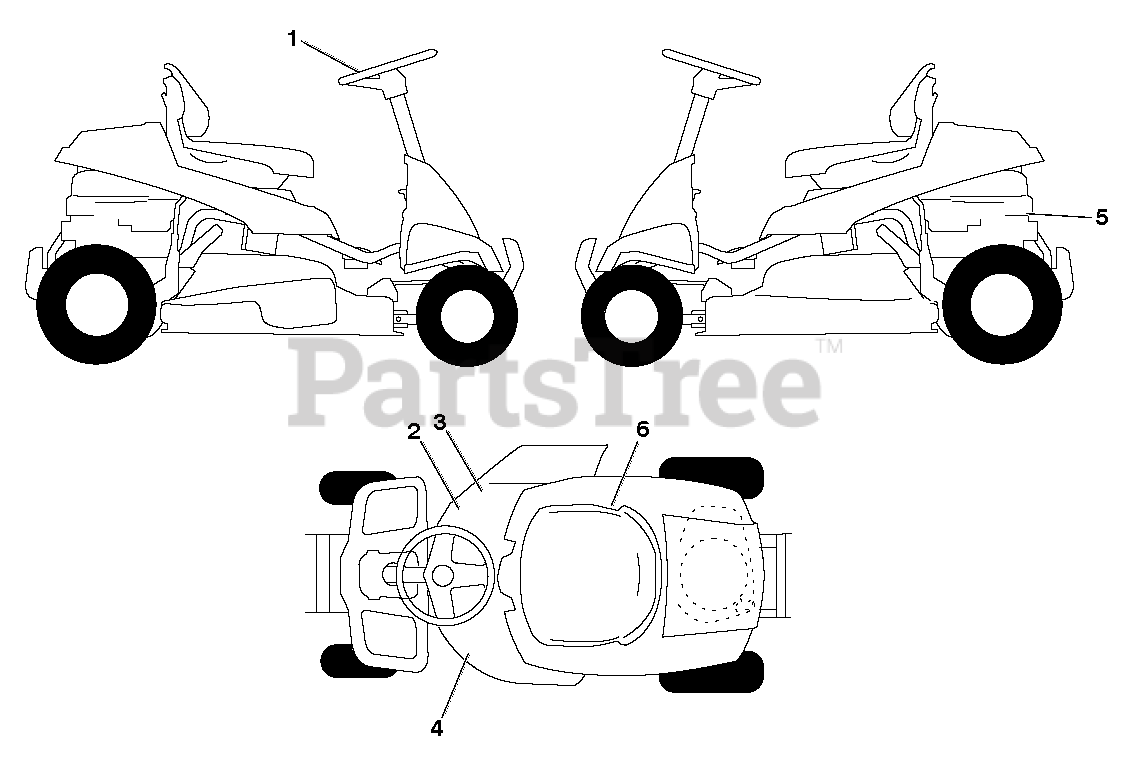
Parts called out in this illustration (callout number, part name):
3	DECAL.WARN.DFLECT/CTFINGR.SRD
4	DECAL.LRVB.DECK.301.PPRO
5	DECAL.ENG.B&S.11.5HP.PWR.BLT
6	DECAL, WARNING SPARK ARRESTOR
